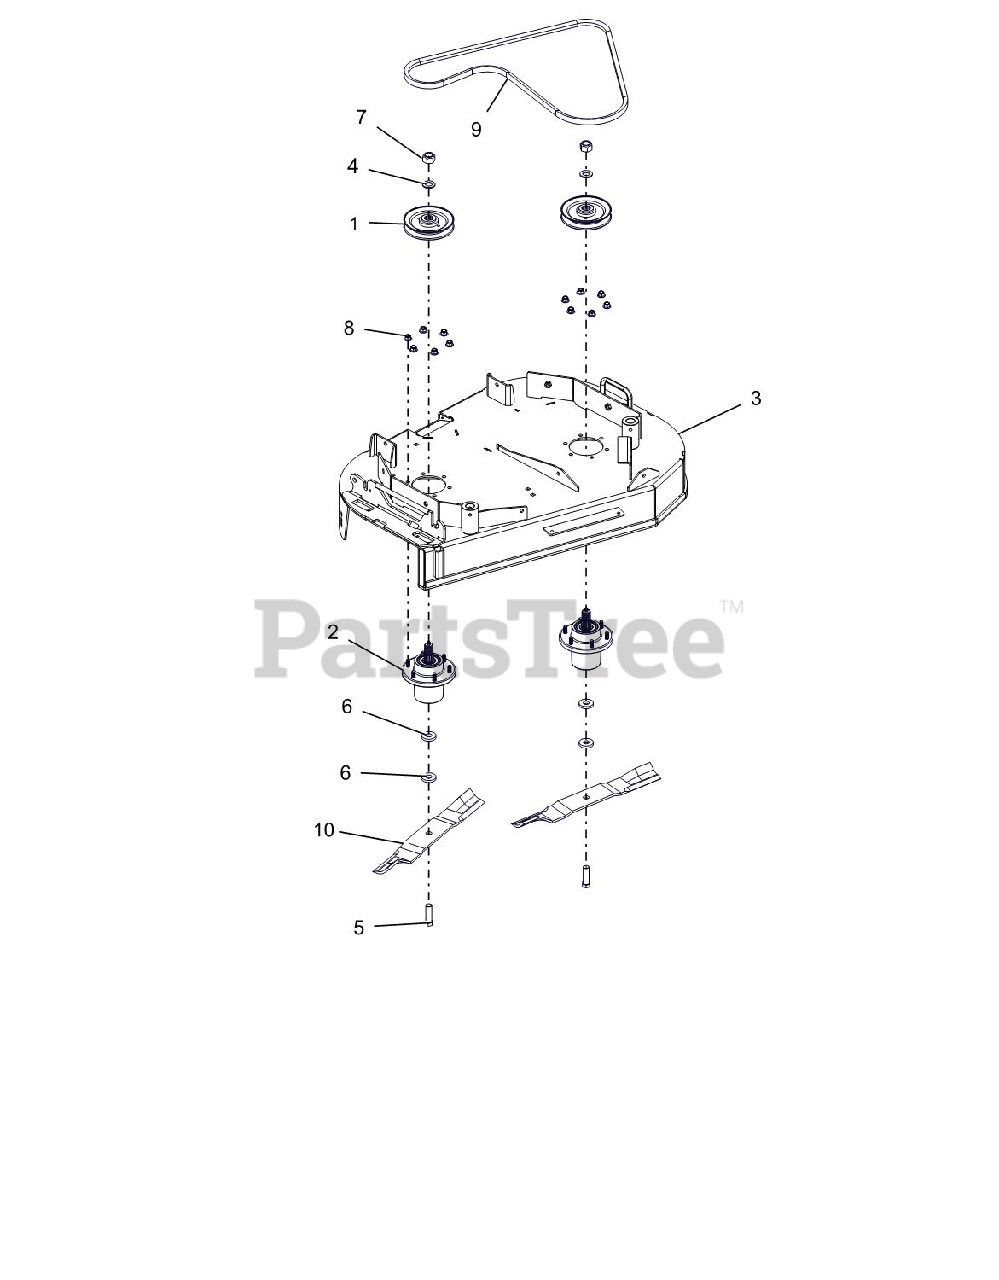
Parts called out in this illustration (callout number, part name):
1	PULLEY, SPINDLE .25 HUB
2	ASSY, SPINDLE HOUSING
3	WLDMT, DECK 36" 2-WHEEL
4	WSHR-FL-STL .75X1.312X.12 ZC12
5	BLT, HEX .62-11X2.00 G8 ZCC
6	WSHR,FLT .630X1.50X.25 ZCC
7	NUT, CROWN LK .750-16 G5 ZC120
8	NUT,LK-NYL-FLG .38-16 G5ZC120
9	V-BELT, HB-RAW EDGE
10	BLADE, 18.00" MOWER (HI-LIFT)
